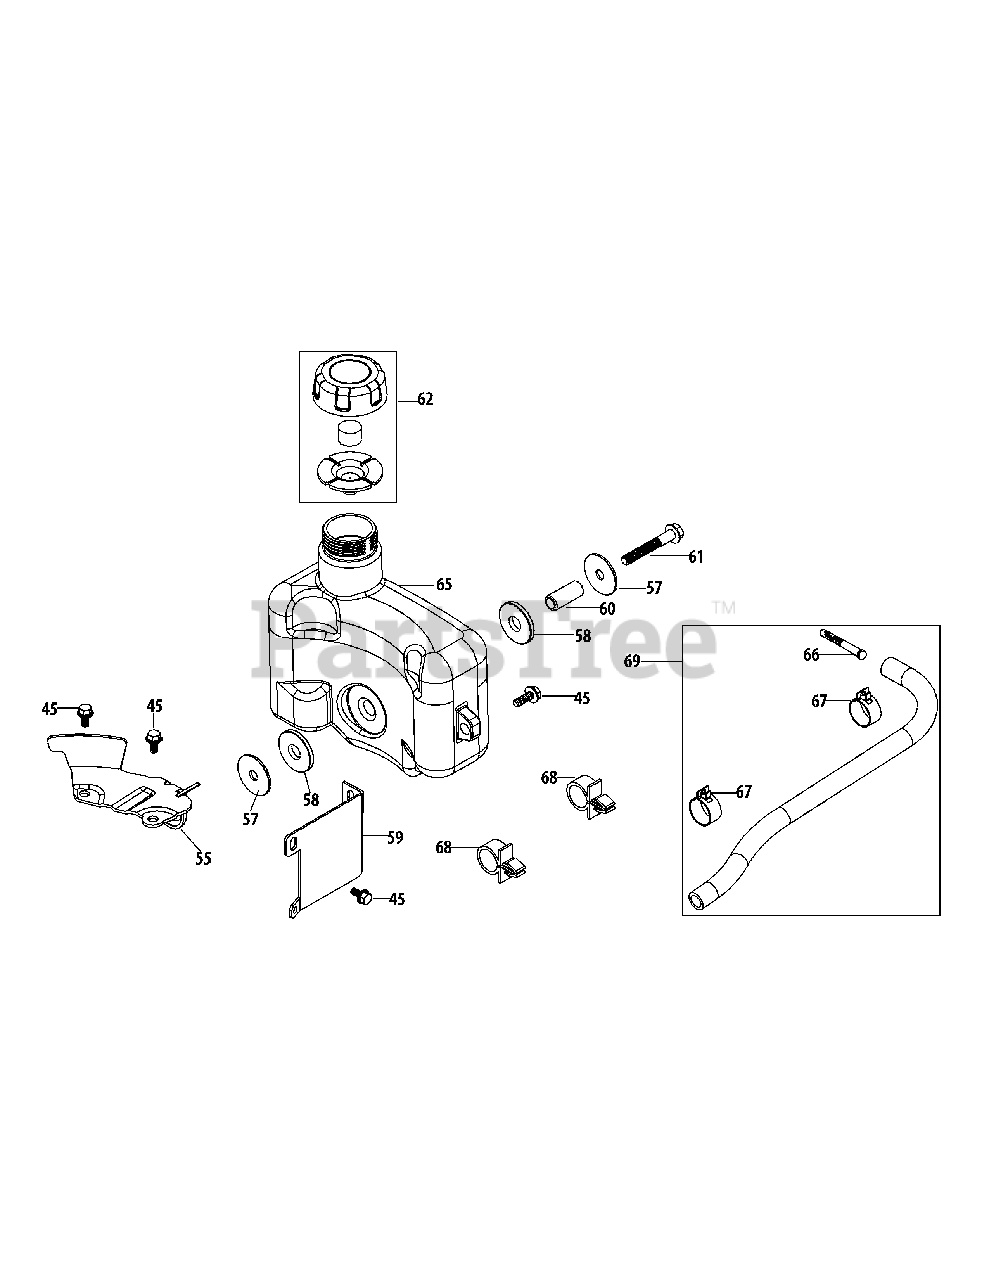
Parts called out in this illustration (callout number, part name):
45	Bolt M6X14
55	Fuel Tank Bottom Bracket
57	Fuel Tank Washer
58	Rubber Bushing
59	Fuel Tank / Label Bracket
60	Fuel Tank Bushing
61	Bolt M8X50
62	Fuel Cap Assembly
65	Fuel Tank Assembly
66	Fuel Filter
67	Fuel Hose Clamp
68	Plastic Support Clamp
69	Fuel Line Kit
